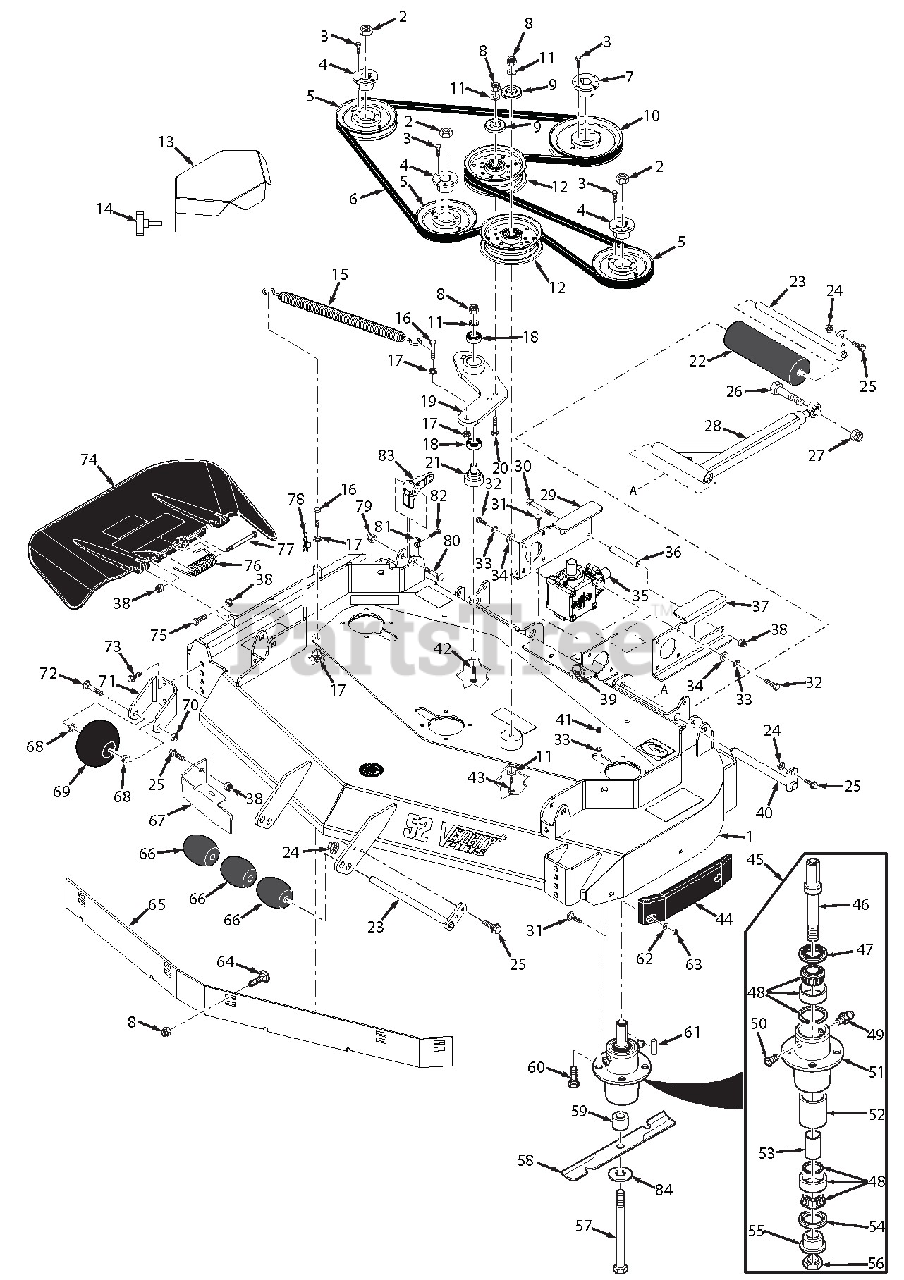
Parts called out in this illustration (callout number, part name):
1	Cutter Deck w/Decals - 52V
2	Nut, 5/8-11 UNC
3	Bolt, Hex Head 1/4-20 x 1" Grade 8
4	Tapered Hub, 1-1/8" Bore
5	Pulley, 5.75 O.D.
6	Belt, Cutter Deck Drive
7	Tapered Hub, 1" Bore
8	Nut, Elastic Stop 3/8-16
9	Dust Shield
10	Pulley, 6.95 O.D.
11	Flatwasher, 3-8/.391 x .938 x .105 HD
12	Pulley, Idler
13	Belt Cover
14	Knob w/Stud
15	Spring
16	Bolt, Hex Head 3/8-16 x 1-1/2" Grade 8
17	Nut, Serrated Flange 3/8-16
18	Bearing
19	Idler Arm Weldment
20	Bolt, Hex Head 3/8-16 x 2-3/4"
21	Pivot, Idler
22	Guide Roller
23	Roller Shaft
24	Nut, Serrated Flange 5/16-18
25	Bolt, Hex Head 5/16-18 x 1"
26	Bolt, Hex Head 5/8-11 x 4-1/2"
27	Nut, Elastic Stop 5/8-11
28	Pusharm Assy., LH
28	Pusharm Assy., RH
29	Mounting Plate
30	Bolt, Hex Head 5/16-18 x 4-3/4"
31	Bolt, Carriage 5/16-18 x 3/4"
32	Bolt, Hex Head 5/16-18 x 1"
33	Lockwasher, 5/16"
34	Flatwasher, 5/16-.375 x .875 x .083
35	Gearbox
36	Spacer
37	Mounting Plate
38	Nut, Elastic Stop 5/16-18
39	Nut, Serrated Flange 5/16-18
40	Shaft Weldment, Pusharm
41	Nut, Elastic Stop 5/16-18 Grade 8
42	Bolt, Hex Head 3/8-16 x 3"
43	Bolt, Hex Head 3/8-16 x 3-3/4"
44	Pad, Deck Wear
45	Spindle Assembly
46	Shaft, Spindle
47	Seal, Top
48	Bearing Assembly
49	Grease Fitting
50	Relief Fitting, Tapered Spindle
51	Spindle Housing
52	Spacer, Outside
53	Spacer, Inside
54	Seal Bottom
55	Spindle Bushing, Bottom
56	Nut, Special 1-1/16 - 18
57	Bolt, Hex Head 5/8-11 x 9-1/2"
58	Cutter Blade, 18"
59	Spacer, Spindle Bottom
60	Bolt, 5/16-18 x 1-3/4" Grade 8
61	Key, 1/4 x 1/4 x 2"
62	Flatwasher, 5/16-.344 x .688 x .065
63	Nut, Center Lock 5/16-18
64	Bolt, Carriage 3/8-16 x 1"
65	Baffle, Custom Cut - 52V
66	Wheel, Anti-Scalp
67	Baffle, Turbo
68	Bushing, .376 I.D. Oilite
69	Anti-Scalp Wheel
70	Nut, Center Lock 3/8-16
71	Bracket, Anti-Scalp
72	Bolt, Carriage 3/8-16 x 4"
73	Bolt, Hex Head Serrated Flange 3/8-16 x 1"
74	Discharge Chute Assy.
75	Bolt, Hex Head 5/16-18 x 1-3/4"
76	Spring, Discharge Chute
77	Bolt, Hex Head 5/16-18 x 4-3/4"
78	U-Nut, 3/8-16
79	Nut, Elastic Stop 7/16-14
80	Bolt, Carriage 7/16-14 x 2-1/4"
81	U-Nut, 3/8-16 (short)
82	Bolt, Hex Head 3/8-16 x 2" Special
83	Lever, Deck Level
84	Flatwasher, 5/8-.688 x 1.75 x .134 HD
